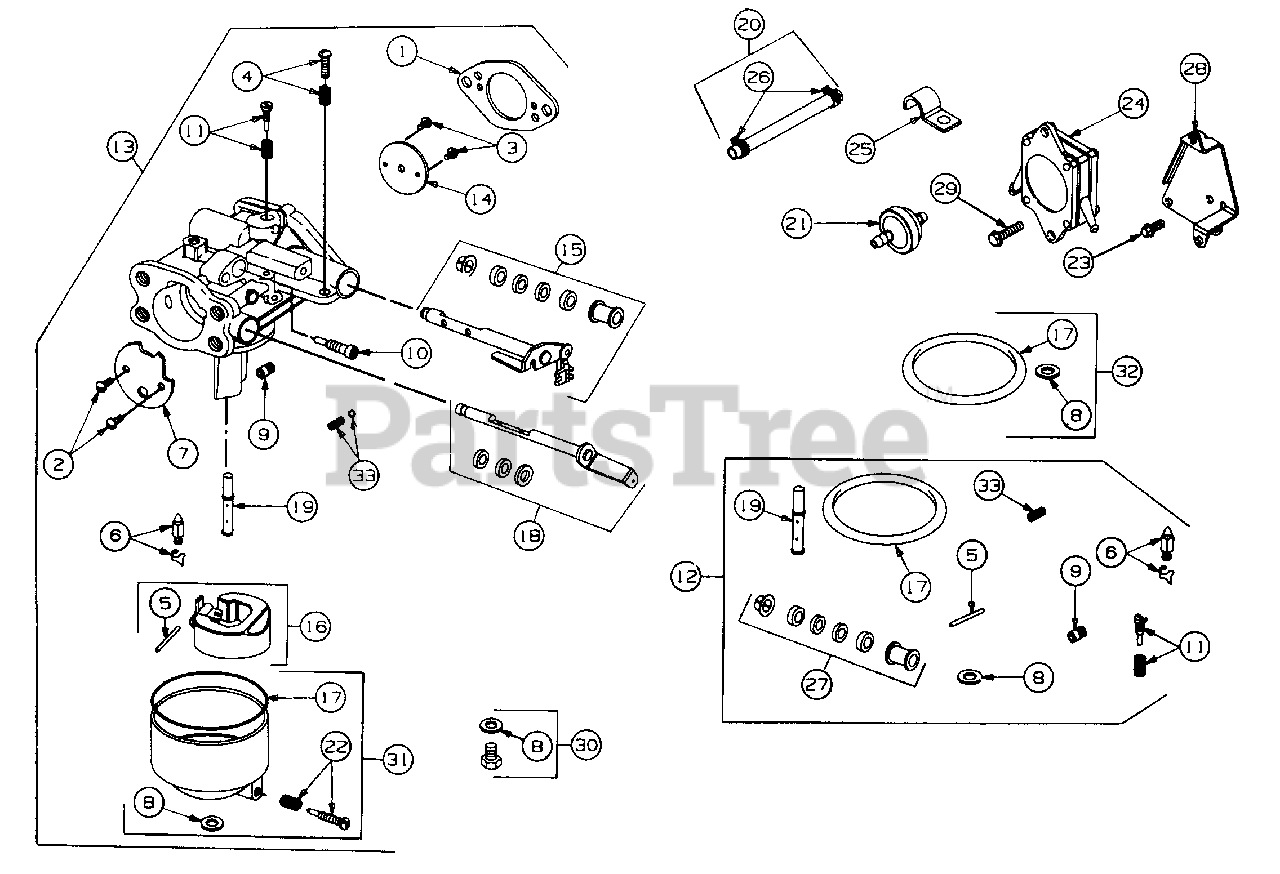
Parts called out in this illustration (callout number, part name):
1	Gasket, Carburetor Mtg
2	Screw, Valve Mtg
3	Screw, Valve Mtg
4	Screw, Throttle Adjustment
5	Pin, Float Hinge
6	Valve, Fuel Inlet
7	Valve, Choke
8	Washer, Bowl
10	Jet, Pilot
11	Valve, Idle Adjustment Needle
12	Carburetor Overhaul Kit
13	Carburetor Assy
14	Valve, Throttle
15	Shaft Assy, Throttle
16	Float, Bowl
17	Gasket, Bowl
18	Shaft, Choke
19	Nozzle, Carburetor
20	Hose Fuel, 11" Lg
21	Filter, Fuel
22	Drain, Carburetor Bowl
23	Screw, Sem
24	Pump, Fuel
25	Clamp, Fuel Pipe
26	Clamp, Hose
27	Seal Kit, Shaft
28	Bracket, Fuel Pump
29	Screw, Mtg
30	Screw, Fuel Bowl
31	Bowl Assy, Fuel
32	Gasket Set, Carburetor
33	Ball, Choke Locator
